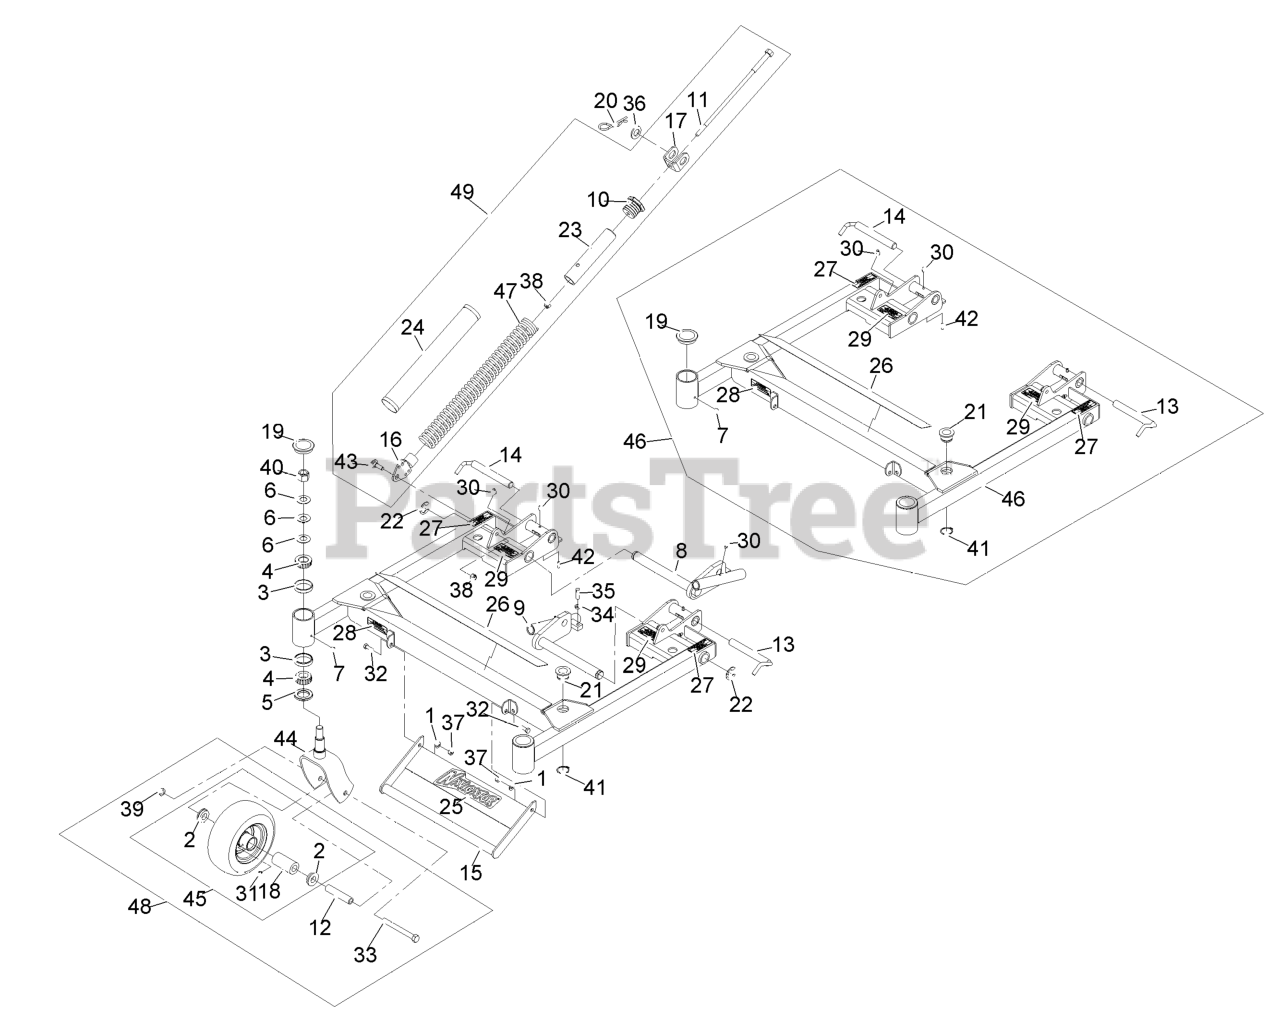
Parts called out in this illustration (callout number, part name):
1	WASHER-SPRING
2	BUSHING
3	CUP-BEARING
4	Cone-Bearing Tapered Roller
5	SEAL-GREASE
6	WASHER-BELLVILLE
8	PIVOT-DECK, RH
9	PIVOT-DECK, LH
10	PLUG-ADJUSTER, SPRING
11	SHAFT-ADJUSTMENT, SPRING
12	SPACER-CASTER, FRONT
13	LOCK-DECK, LH
14	LOCK-DECK, RH
15	ASM,DECK LIFT HANDLE W/DE
16	TENSIONER-SPRING
17	MOUNT-LIFT ASSIST, DECK
18	BEARING-ROLLER, STRAIGHT
19	CAP-GREASE
20	PIN-CUT HEIGHT
21	BUSHING-SUPPORT, DECK
22	RING-SNAP
23	SPRING-TUBE
24	COVER-SPRING, DECK
25	DECAL,NAVIGATOR MODEL
26	PAD-ANTI SKID
27	DECAL-FOLDING DECK
28	DECAL-DANGER
29	DECAL-SPRING
30	FITTING-GREASE
31	FITTING-GREASE
32	SCREW-HH
33	SCREW-HH
34	NUT-JAM
35	SCREW-SET, SQH
36	WASHER-FLAT
37	NUT-LOCK, NI
38	NUT-LOCK, NI
39	NUT-HEX
40	NUT-LOCK, NI
41	RING-RETAINING
42	PIN-SPRING
43	SCREW-SHOULDER, HWH
44	FORK-CASTER
45	ASM,WHEEL,TIRE & BRGS 8X3
46	DECK SUPPORT ASM
47	SPRING-EXTENSION
48	ASM,FF CASTER WHEEL W/AXL
49	ASM,LIFT AST SPRING
